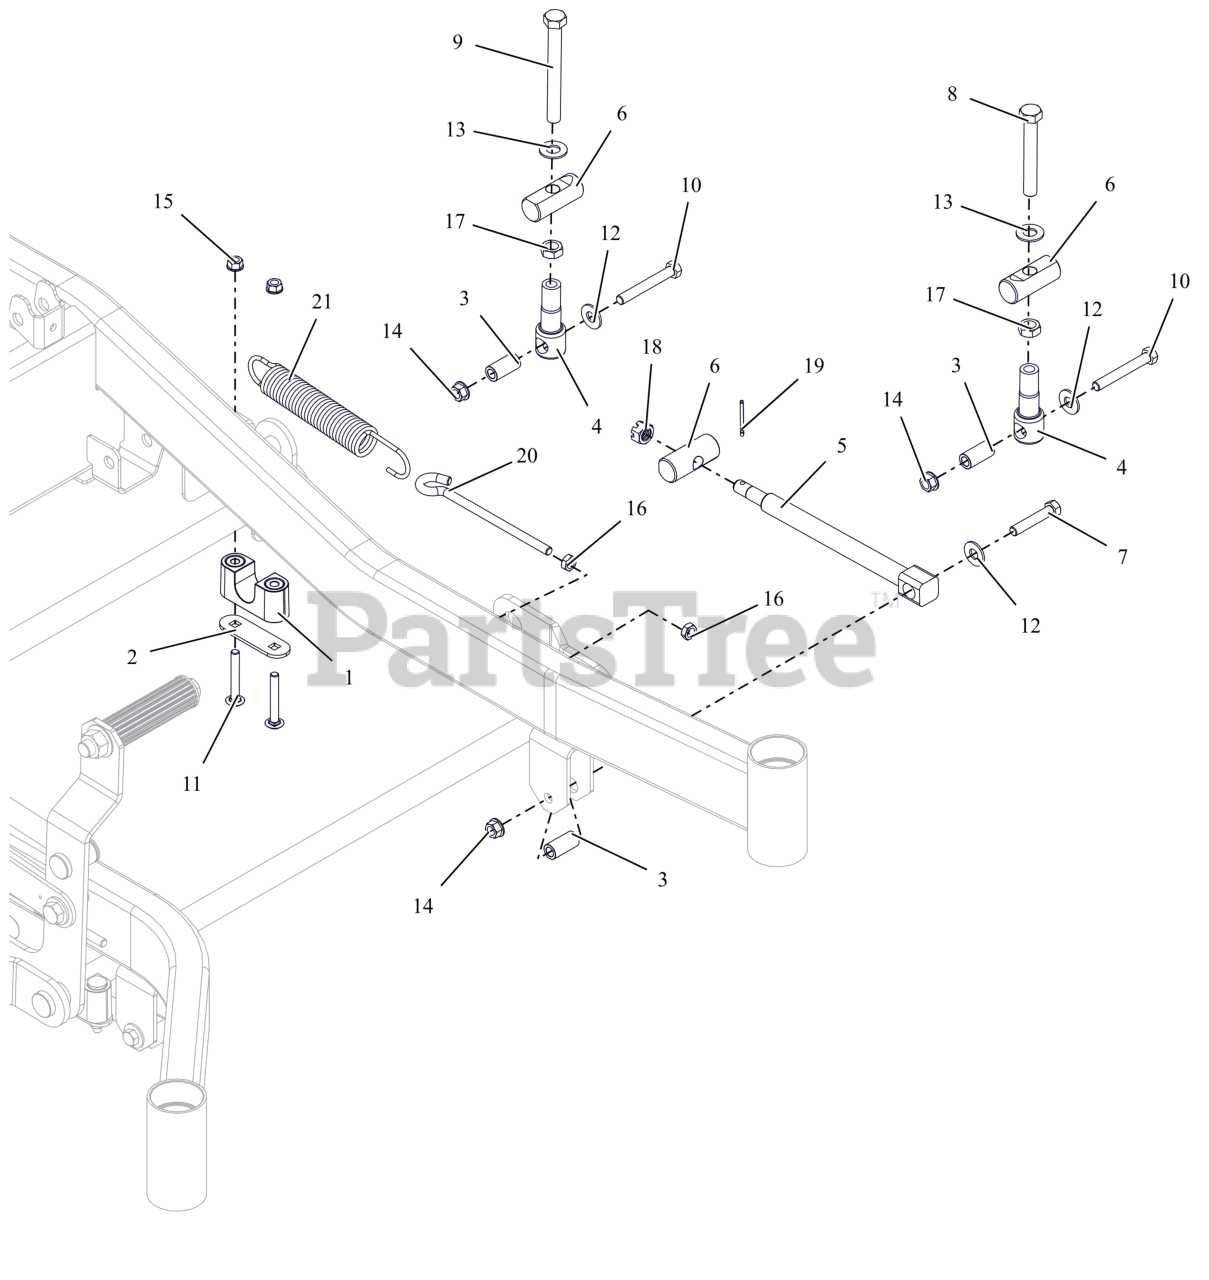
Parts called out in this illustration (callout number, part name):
1	ASM-BUSHING, DECK LIFT
2	PLATE, BEARING SUPPORT
3	SPACER, DECK LEVELING
4	LINK, DECK LIFT FORMED
5	DRAG,LINK-HD
6	PIN, DECK LIFT
7	BLT,HEX .38-16X2.00 G5 ZCC
8	BLT, HEX .50-13X3.50F G5 ZCC
9	BLT, HEX .50-13X4.50F G8 ZCC
10	BLT, HEX .38-16X2.75 G8 ZCC
11	BLT, RHSSN.31-18X2.25 G5 ZCC
12	WSHR,FLT .438X1.00X.083 ZCC
13	WSHR, FLT .557X1.040X.102 ZCC
14	NUT-LK-TOP-FLG .38-16 ZC120
15	NUT,LK-CTR-FLG .31-18 GF ZCC
16	NUT-JAM .375-16 G2 ZCC
17	NUT-JAM .500-13 G2 ZCC
18	NUT-SL .50-13
19	PIN,CTR.12X1.25EXTPRSQCT ZC120
20	BOLT,.38-16 X 5.25-.62 DIA EYE
21	SG-TENS .162X1.25X8.25 WLD 25
